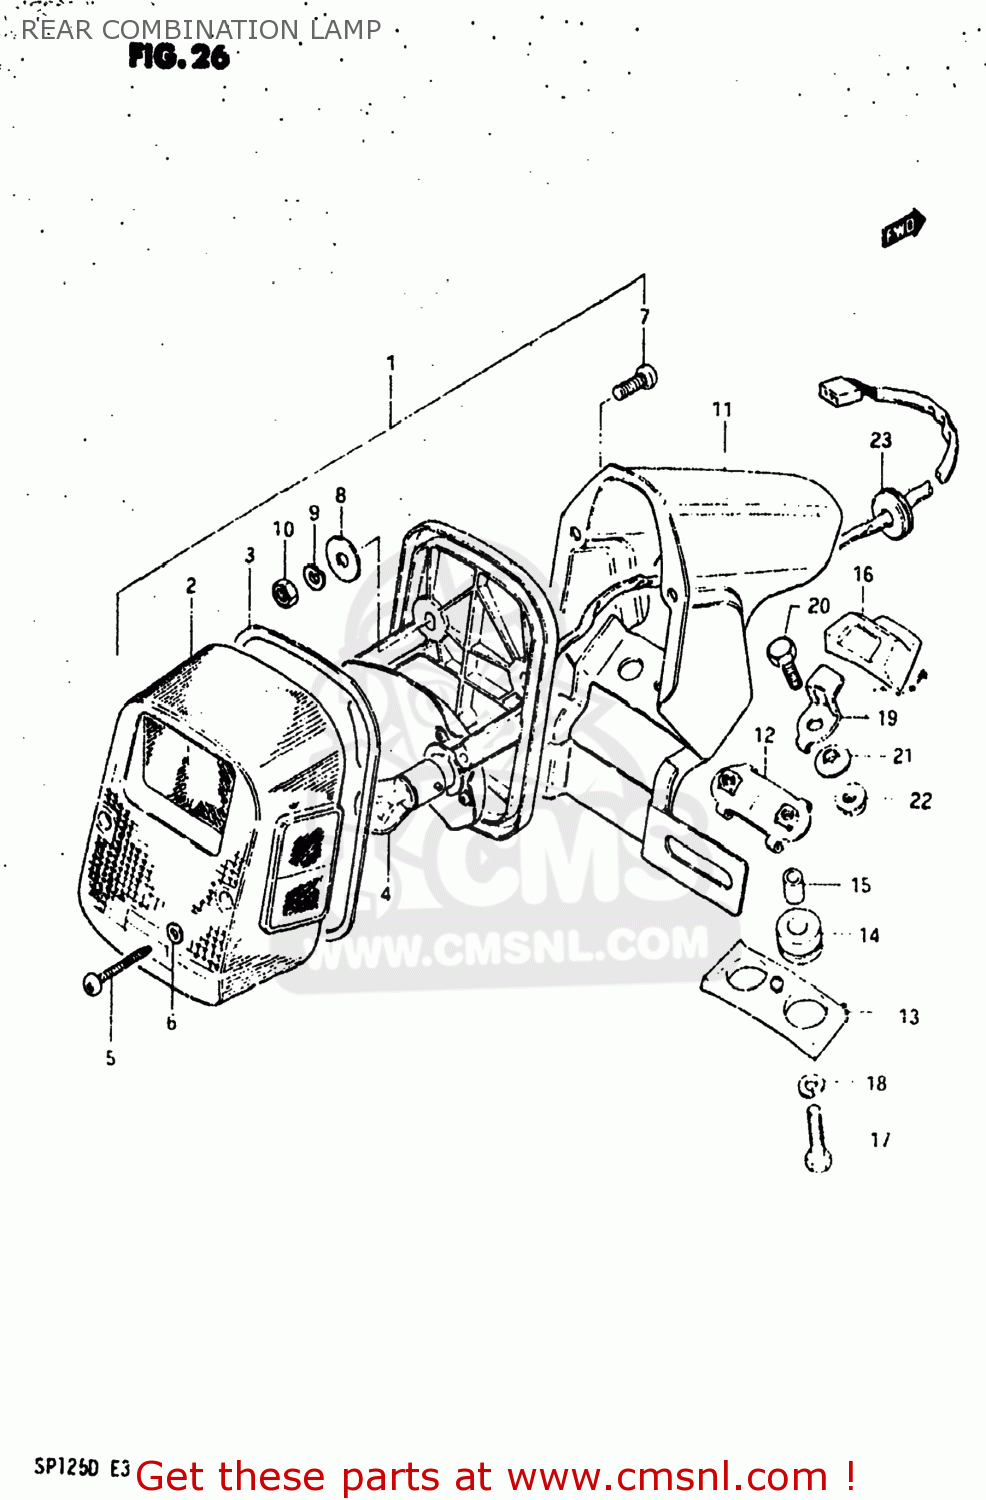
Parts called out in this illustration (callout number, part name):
1	LAMP UNIT,REAR COMBINATION
2	LENS
3	GASKET (NAS)
4	BULB(6V32/3CP,STANLEY)
5	SCREW TAPP.
6	GASKET (NAS)
7	SCREW
8	WASHER,REAR COMBINATION LAMP
9	LOCK WASHER
10	NUT
11	BRACKET UNIT,TAIL LAMP
12	PLATE
13	CUSHION
14	CUSHION
15	SPACER
16	CUSHION,REAR COMBINATION LAMP
17	BOLT
18	LOCK WASHER
19	PLATE,RR COMBINATION LAMP
20	BOLT, UPPER
21	WASHER,LOCK
22	NUT
23	GROMMET
